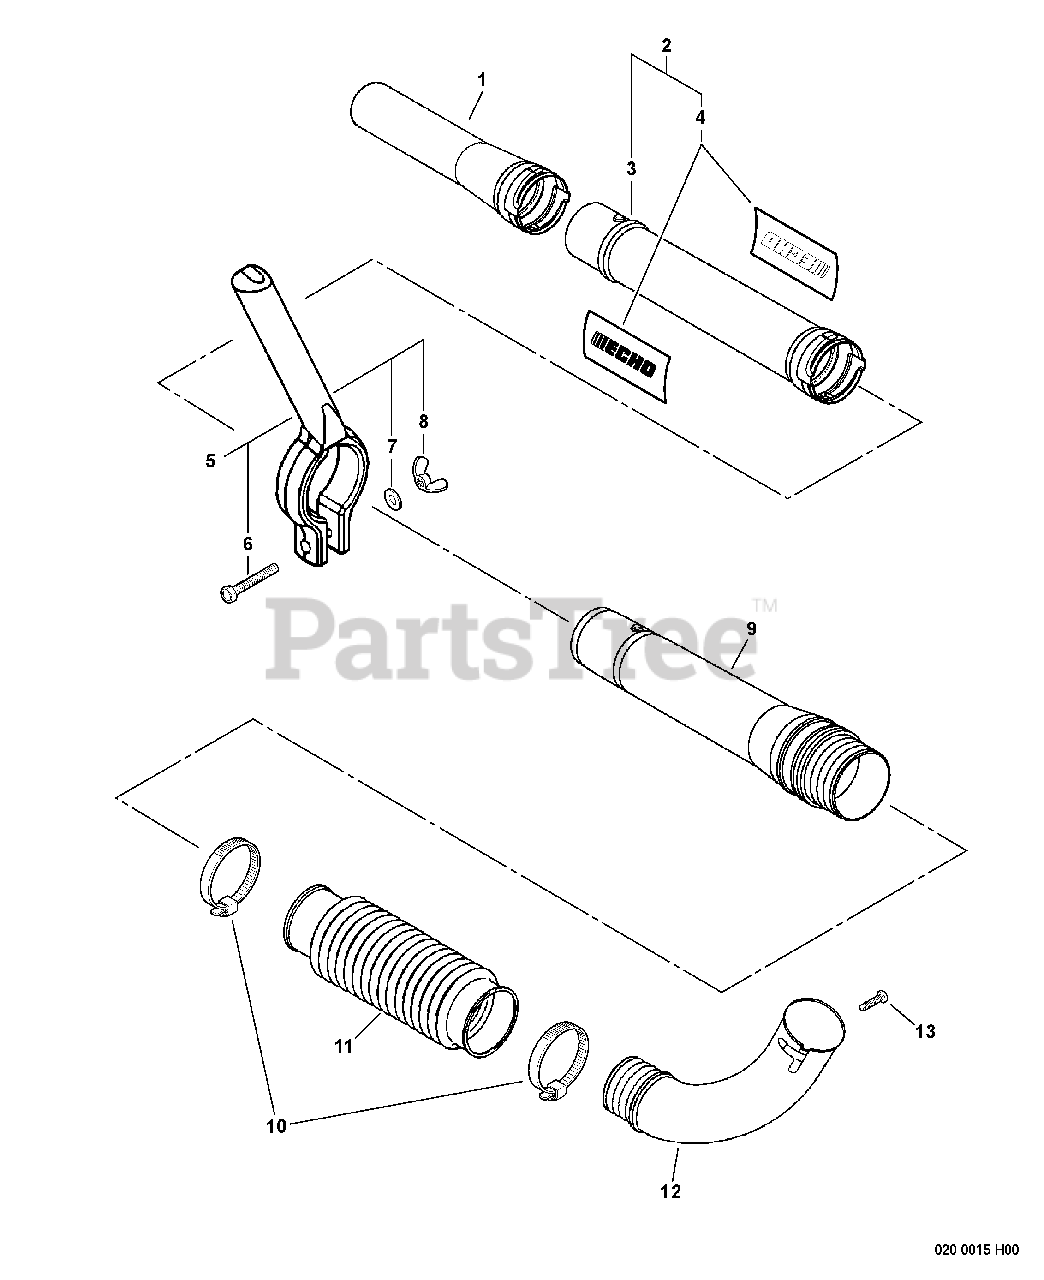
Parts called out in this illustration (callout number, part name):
1	TUBE, BLOWER - NOZZLE
2	BLOWER TUBE KIT - STRAIGHT
3	TUBE, BLOWER - STRAIGHT
4	LABEL - ECHO
5	HANDLE ASSY
6	BOLT - 6X45
7	WASHER - 6
8	WINGNUT - 6
9	TUBE, BLOWER - SWIVEL
10	CLAMP, HOSE
11	TUBE, BLOWER - FLEXIBLE
12	TUBE, BLOWER - ELBOW
13	SCREW - 5X10
